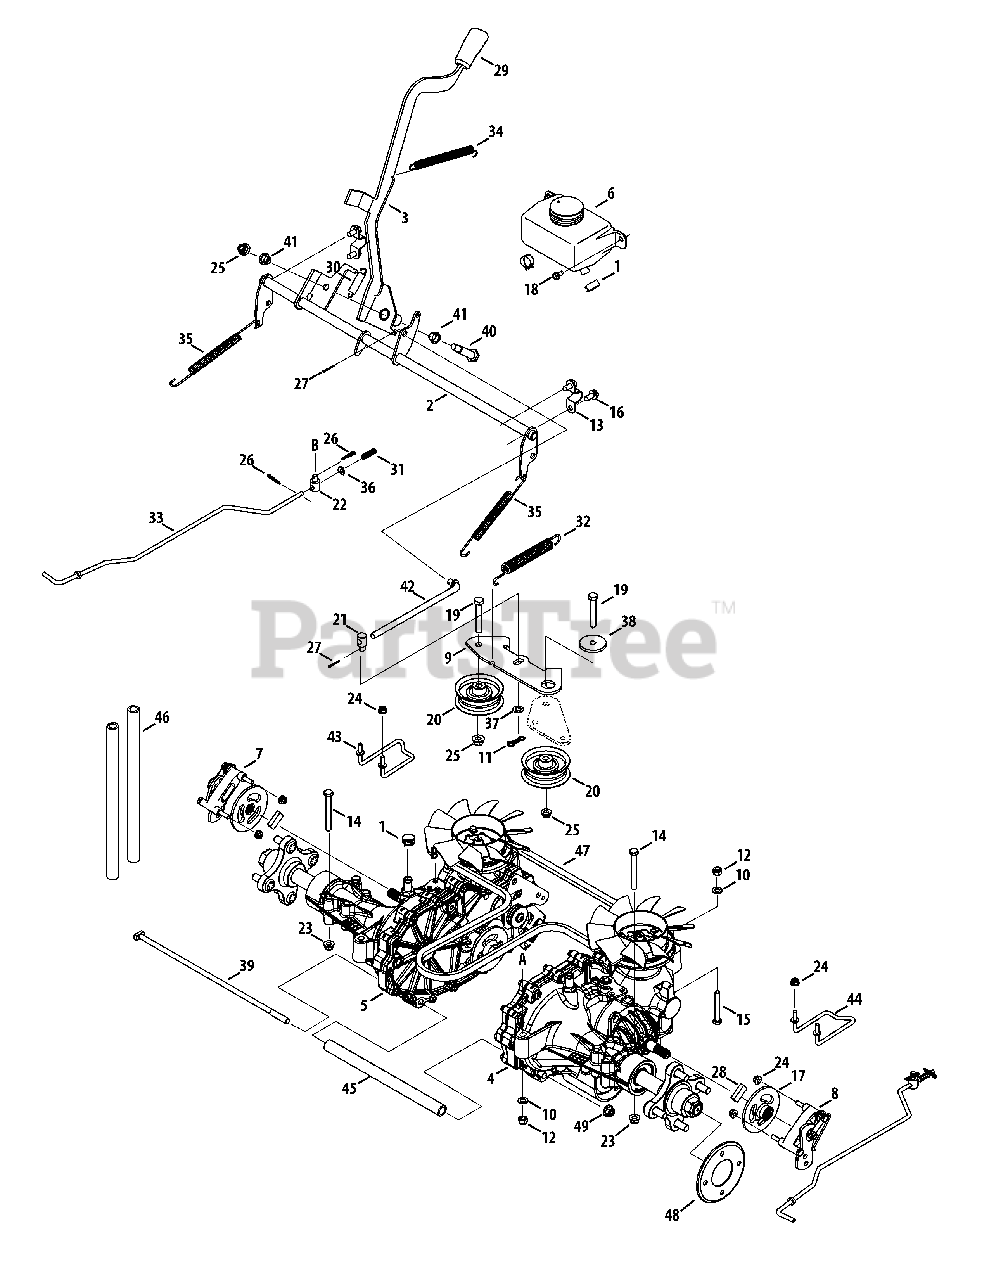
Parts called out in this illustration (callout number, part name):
1	Hose Clamp, 1/2"
2	Brake Shaft Assembly
3	Brake Handle Assembly
4	RH Transmission Assembly
5	LH Transmission Assembly
6	Expansion Tank Assembly
7	LH Brake Assembly
8	RH Brake Assembly
9	Idler Bracket
10	Flat Washer, .330 x .630 x .064
11	Bow-Tie Cotter Pin
12	Hex Lock Nut, 5/16-24
13	Shaft Mount Bracket
14	Hex Screw, 5/16-18 x 2.75
15	Hex Screw, 5/16-24 x 2.25
16	Hex Washer Screw, 5/16-18 x .750
17	Brake Disc
18	Hex Washer Screw, 1/4-20 x .500
19	Hex Screw, 3/8-16 x 2.25
20	Flat Idler Pulley, 2.75
21	Ferrule, 3/8-24 x .375
22	Ferrule, .325 x .312
23	Flange Lock Nut, 5/16-18
24	Flange Lock Nut, 1/4-20
25	Flange Lock Nut, 3/8-16
26	Cotter Pin, .072 x 1.13
27	Cotter Pin, 3/32 x .750
28	Brake Pad
29	Selector Handle
30	Extension Spring, .48 x 2.03
31	Compression Spring, .405 x 1.17
32	Extension Spring, .75 x 6.02
33	Transmission Bypass Lever Wire
34	Extension Spring, .50 x .6.37
35	Extension Spring, .500 x 7.0
36	Spring Washer, .265 x .562 x .025
37	Thrust Washer, .375 x .70 x .030
38	Shoulder Spacer, .884 x .190
39	Rod, .405 x 14.00
40	Shoulder Screw, .498 x 1.635
41	Flange Bearing, .500 x .34
42	Disengage Brake Rod
43	LH Rod Keeper
44	RH Rod Keeper
45	Transmission Spacer, 10.5
46	Fuel Hose, 1/2 x 12.00
48	Reinforcement Plate
49	Flange Lock Nut, 7/16-20
